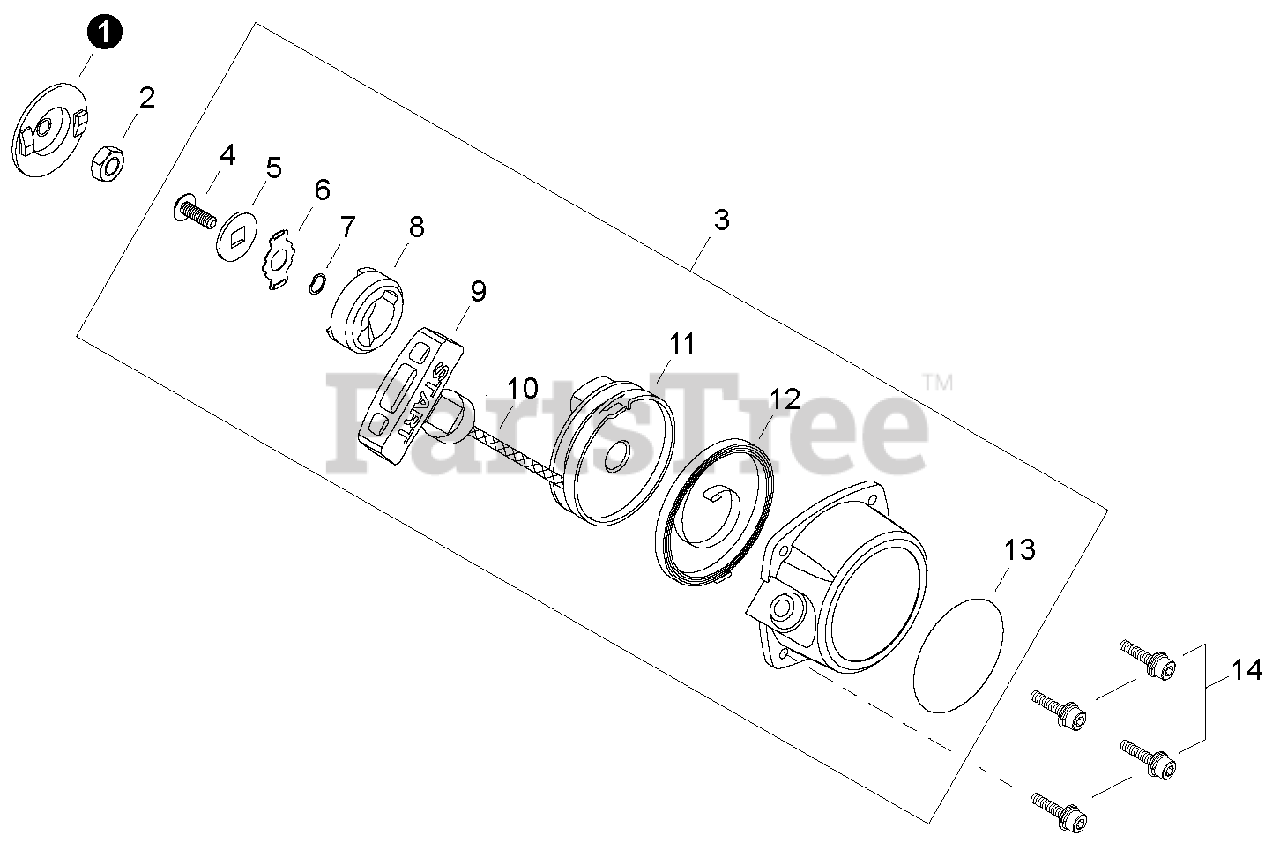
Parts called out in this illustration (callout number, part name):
1	PULLEY, STARTER
2	NUT M8×1
3	STARTER ASSY, RECOIL
4	SCREW 5 MM
5	WASHER 5 MM
6	RETAINER
7	WASHER, WAVE
8	RATCHET
9	GRIP, STARTER
10	ROPE, STARTER
11	REEL, ROPE
12	SPRING, RECOIL
13	LABEL, RECOIL STARTER
14	SCREW M4×12
